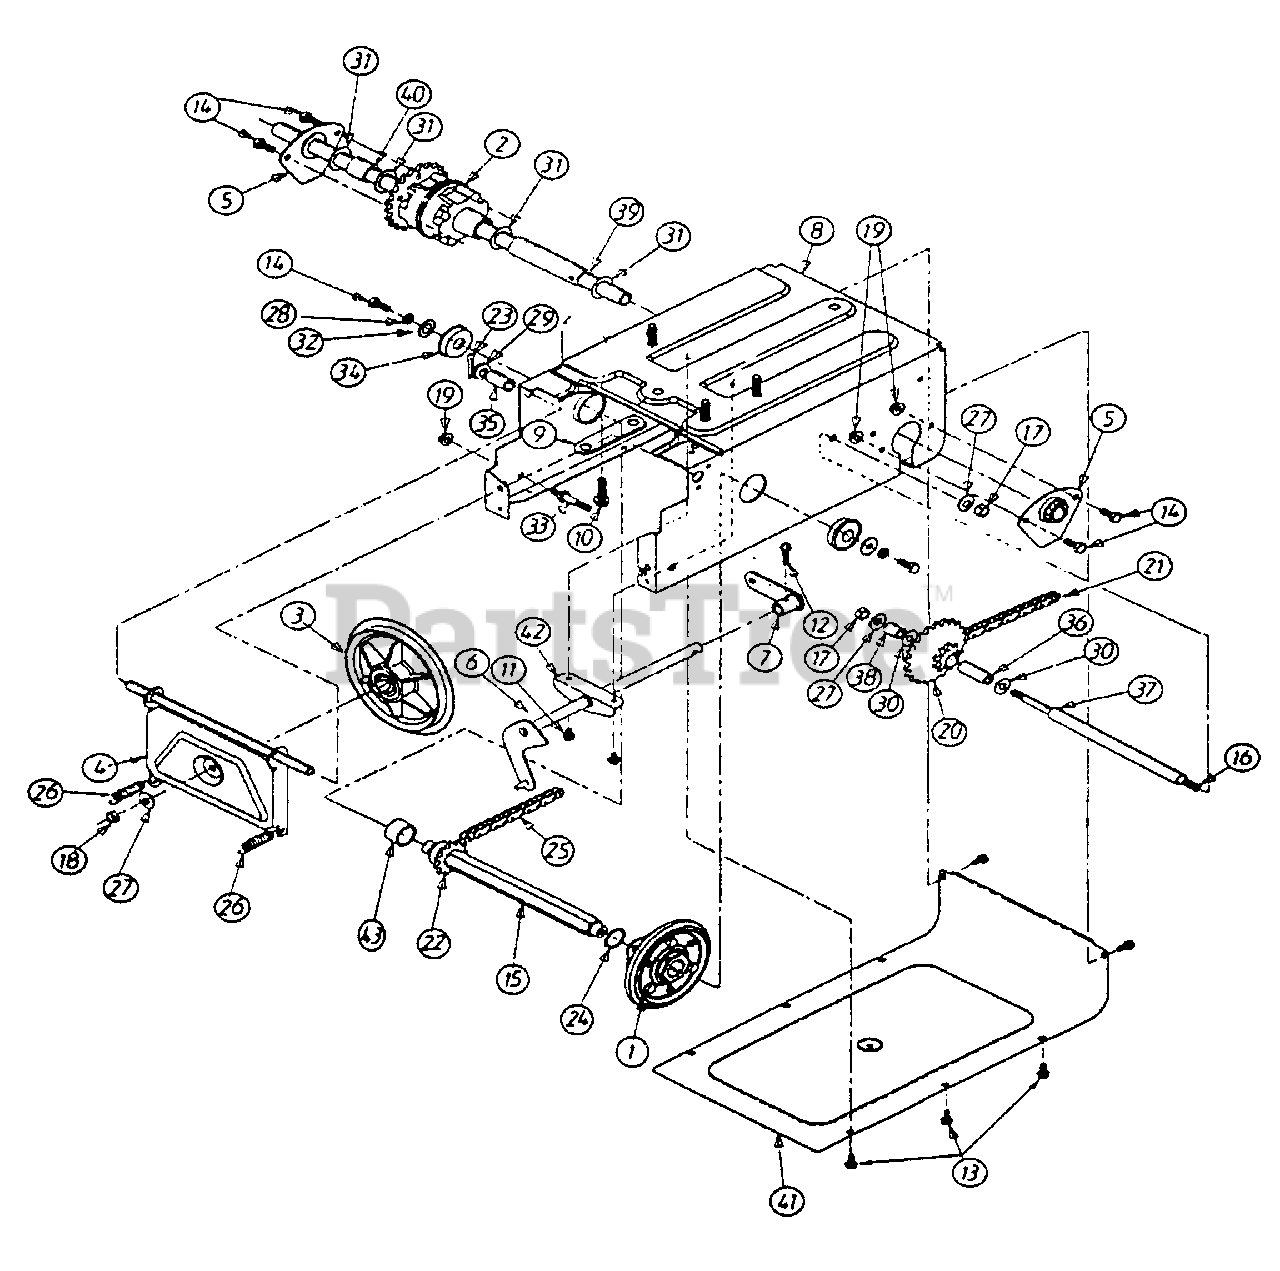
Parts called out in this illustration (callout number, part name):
1	FRICTION WHEEL ASSY
2	DIFFERENTIAL ASSY COMP.
3	FR. WHEEL DISC ASSY
6	SHAFT ASSY-SHIFT
11	SCREW-HEX WASHER
12	SCREW-HEX WASHER
13	SCREW-HEX
14	SCREW-HEX
15	SHAFT-HEX
16	SHAFT-JACK
17	NUT-HEX
18	NUT-HEX JAM
19	NUT-HEX FLANGE LOCK
20	SPROCKET & HUB
21	CHAIN
22	SPROCKET 107
23	COTTER PIN
24	SNAP RING
25	CHAIN
26	EXTENSION SPRING
27	WASHER-BELL
28	WASHER-LOCK
29	WASHER-FLAT
30	WASHER-FLAT
31	WASHER-FLAT
32	WASHER-FLAT
33	IDLER BOLT
34	BALL BEARING
35	SPACER
36	SLEEVE
37	SPACER
38	SPACER
39	SPACER
40	SPACER
43	SPACER
